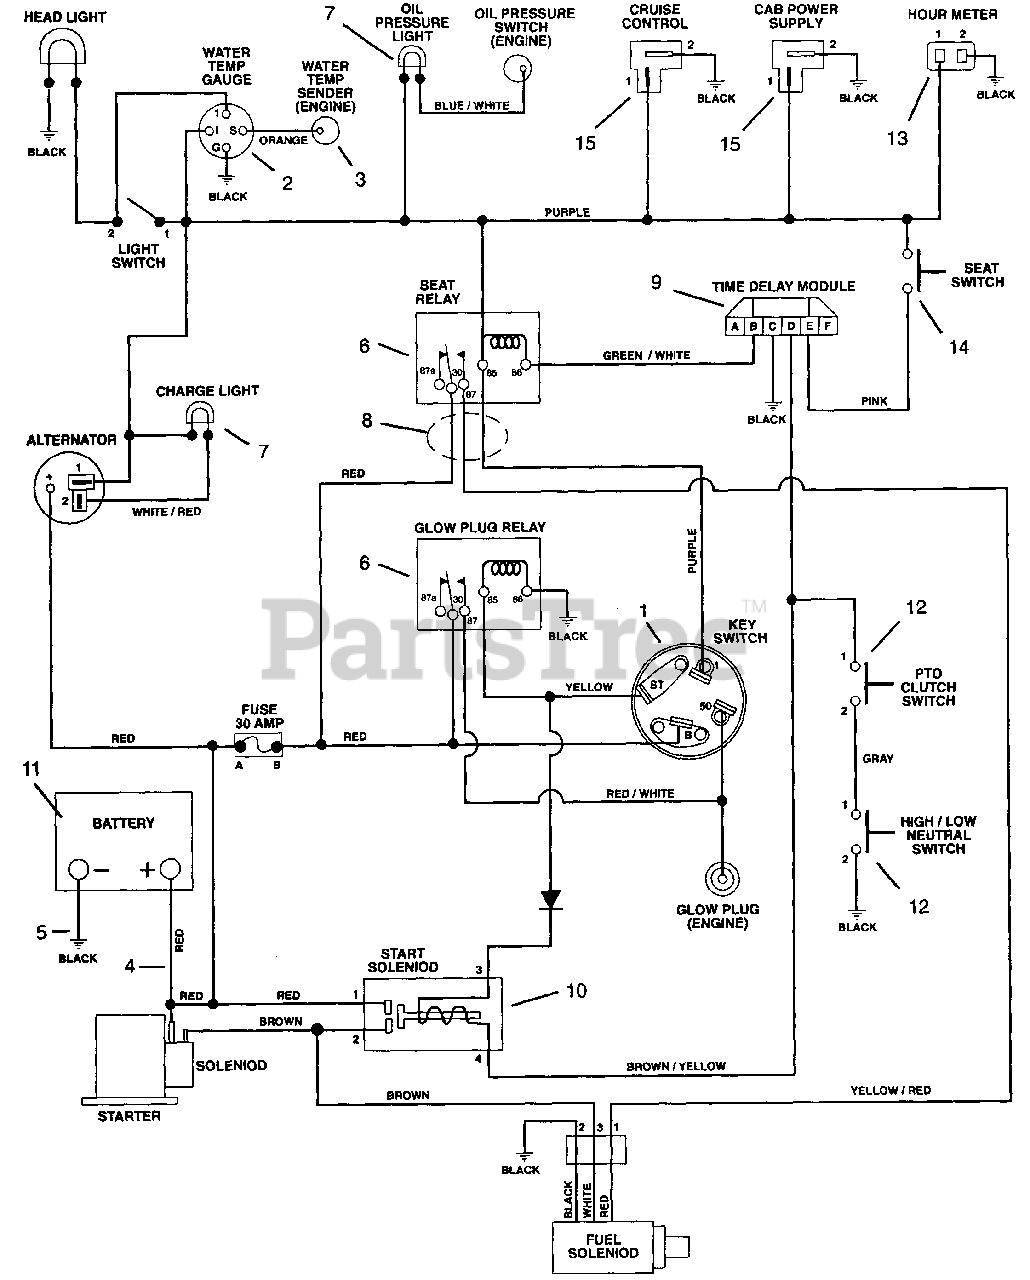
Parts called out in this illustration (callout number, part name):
1	Switch, Ignition
2	Gauge, Temperature
3	Sender, Temperature
4	Cable, Positive Battery
5	Cable, Negative Battery
6	Relay
7	Light, Indicator
8	Wire Harness - Kubota
9	Module, Interlock, Delay 1801
10	Solenoid
11	Battery 24F
12	Switch-Neutral Start N.O.
13	Hour, Meter
14	Switch-Seat
15	Cover-Switch
